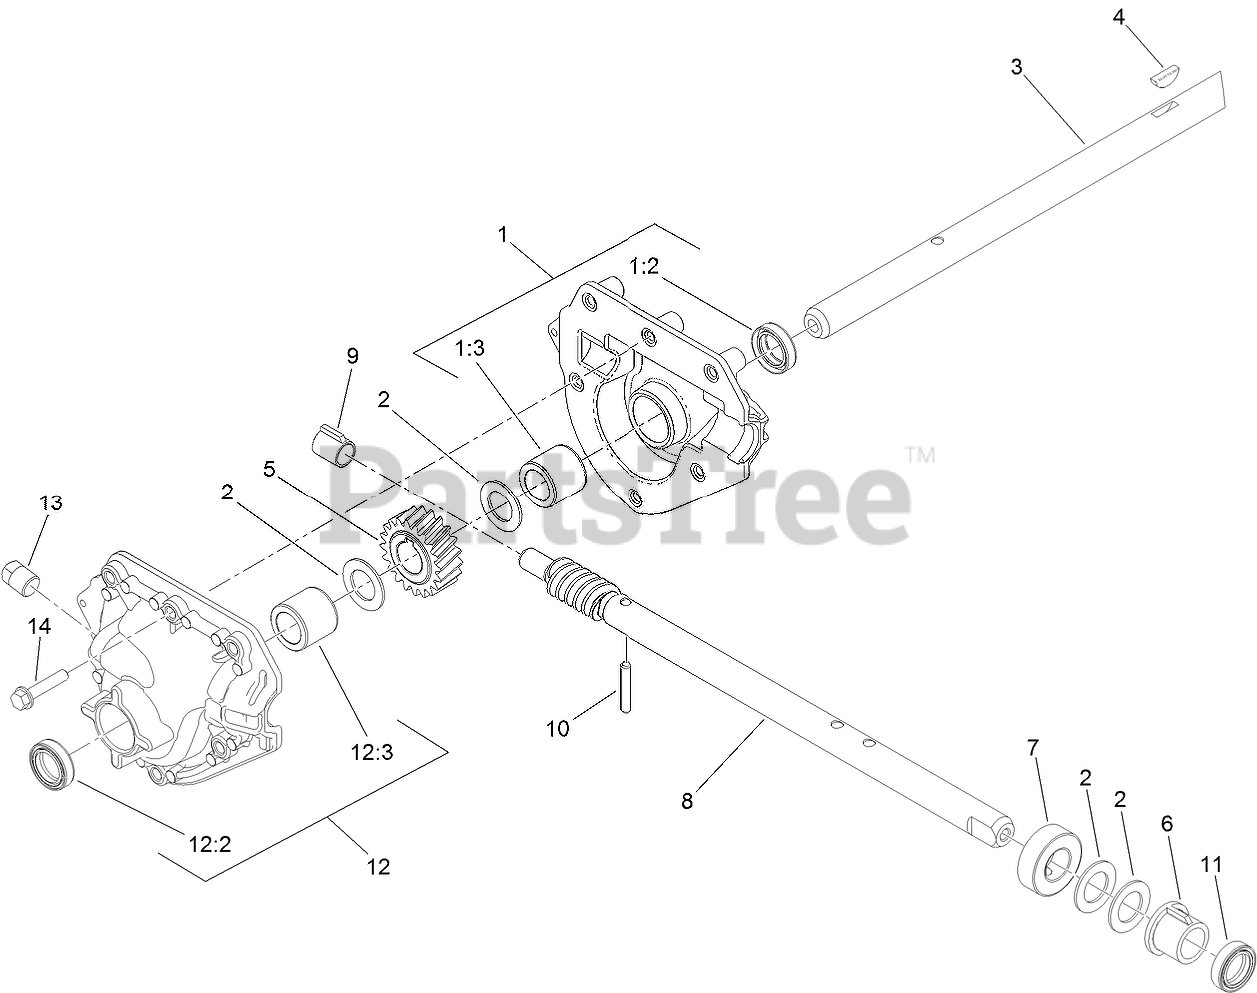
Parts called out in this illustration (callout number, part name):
1	RH AUGER GEARCASE ASM
1:2	SEAL-SHAFT
1:3	BUSHING-SLEEVE
2	WASHER-THRUST
3	SHAFT-OUTPUT, AUGER
4	KEY-WOODRUFF
5	GEAR-HELICAL, 20 TOOTH
6	BUSHING-INPUT
7	COLLAR-THRUST
8	SHAFT-IMPELLER, ROLLED
9	BUSHING-WORM
10	PIN-DOWEL
11	SEAL-SHAFT
12	LH AUGER GEARCASE ASM
12:2	SEAL-SHAFT
12:3	BUSHING-SLEEVE
13	PLUG-PIPE, SQH
14	SCREW-HWHTF
